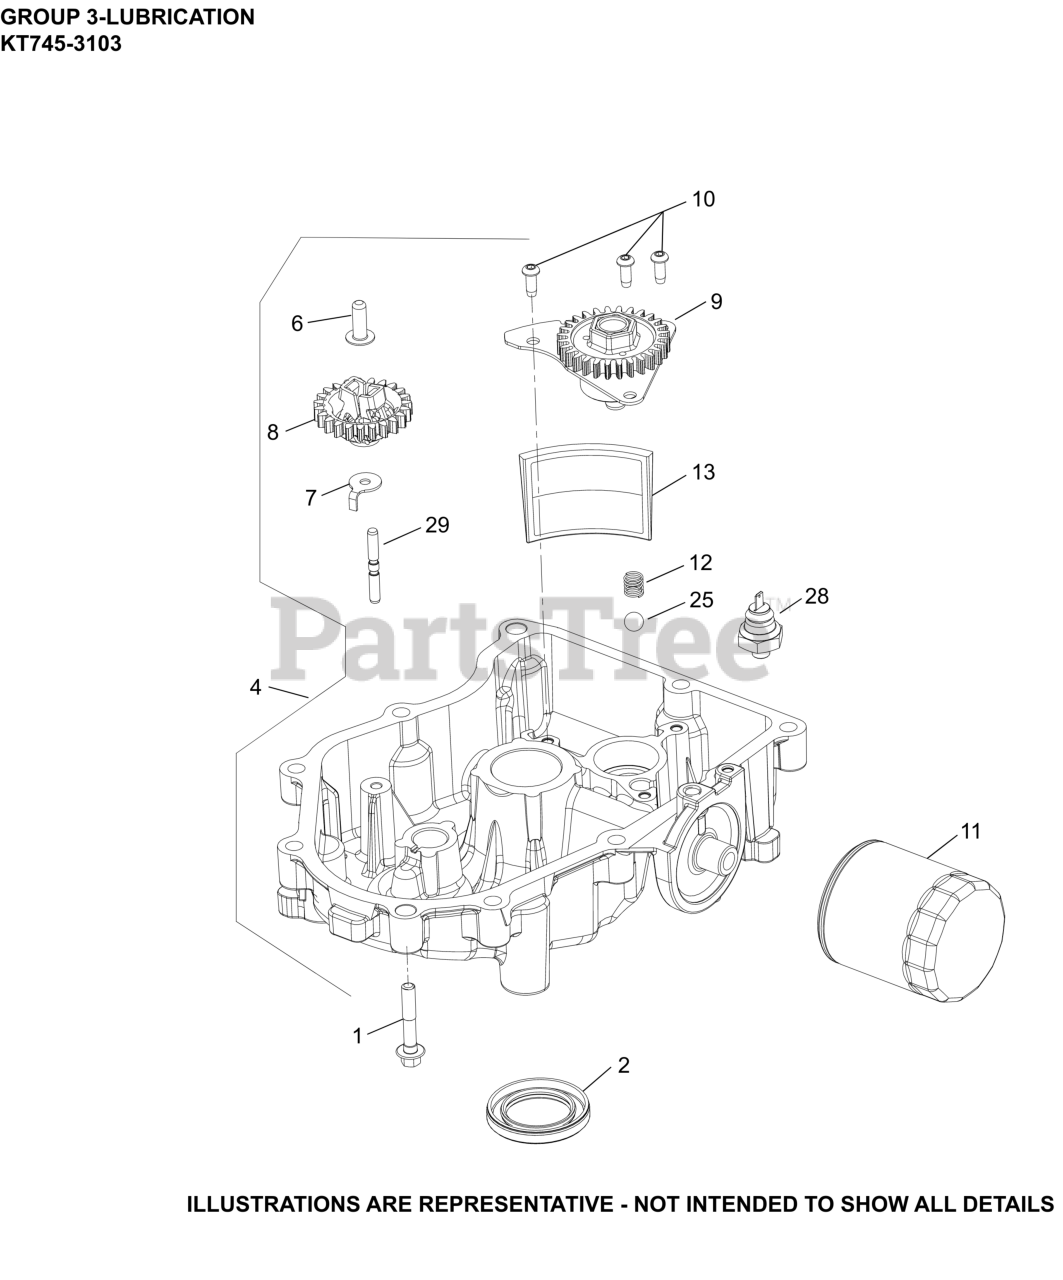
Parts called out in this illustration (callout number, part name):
1	SCREW, FLG M8X1.25X45
4	OIL PAN ASSEMBLY, (ROLLER BURNISHED)
6	PIN, GOVERNOR REGULATING
7	TAB, LOCKING
8	KIT, GOVERNOR GEAR
9	PUMP ASSEMBLY, OIL
10	SCREW, BUTTON HEAD
11	OIL FILTER
12	SPRING, COMPRESSION
13	SCREEN, OIL
25	PRESSURE RELIEF BALL
28	SWITCH, OIL PRESSURE(NC 3-6 PSI TO OPEN)
29	SHAFT, GOVERNOR GEAR
NI	PLUG, PIPE CTSK 3/8"
